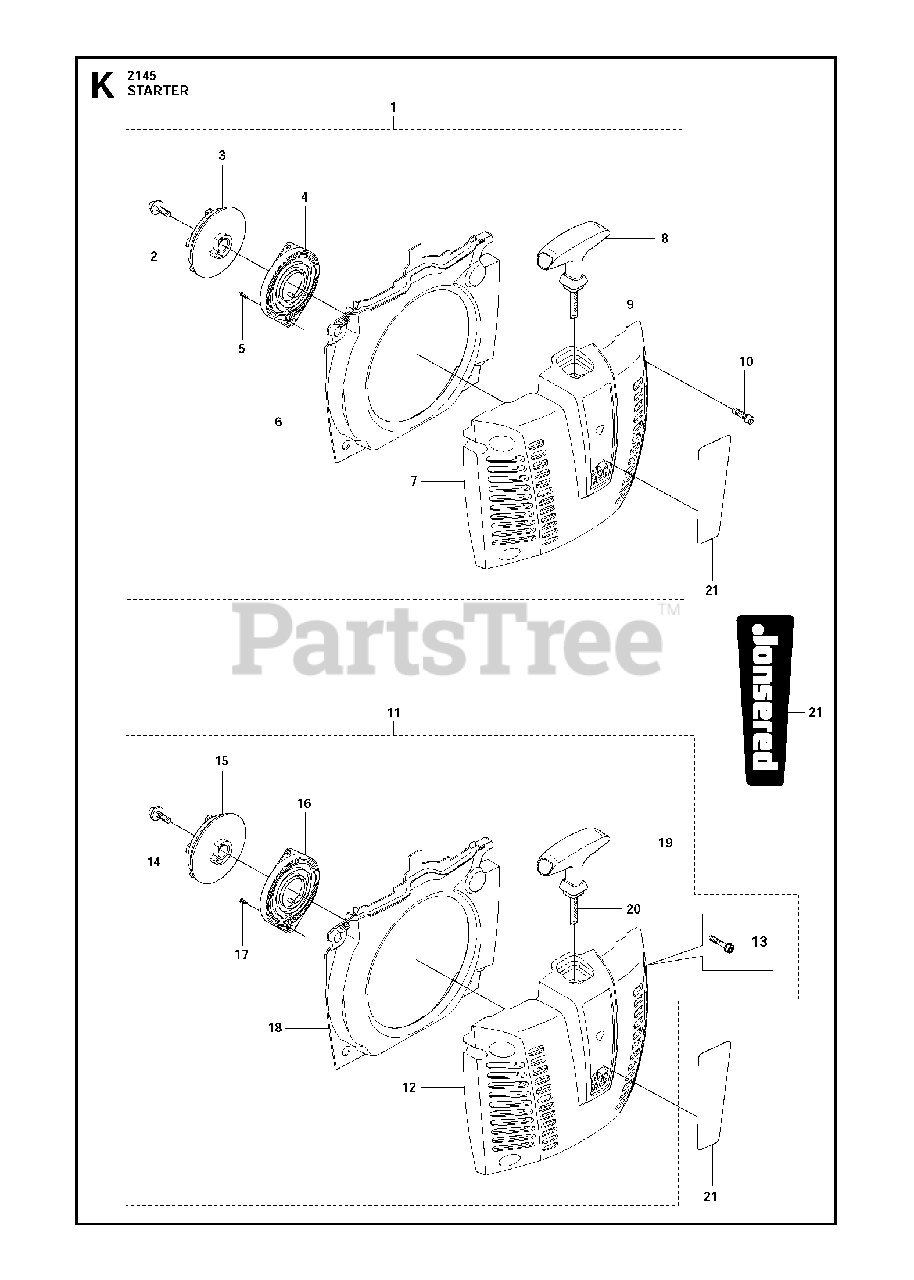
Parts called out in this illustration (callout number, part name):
2	SCREW
3	STARTER PULLEY
4	RECOIL SPRING
5	SCREW
6	AIR CONDUCTOR
7	STARTER HOUSING
8	STARTER HANDLE
9	STARTER ROPE
10	SCREW IHSCFM
12	STARTER HOUSING
13	SCREW IHSCFMO
14	SCREW
15	STARTER PULLEY
16	RECOIL SPRING
17	SCREW
18	AIR CONDUCTOR
19	STARTER HANDLE
20	STARTER ROPE
21	STARTER HOUSING DECAL
